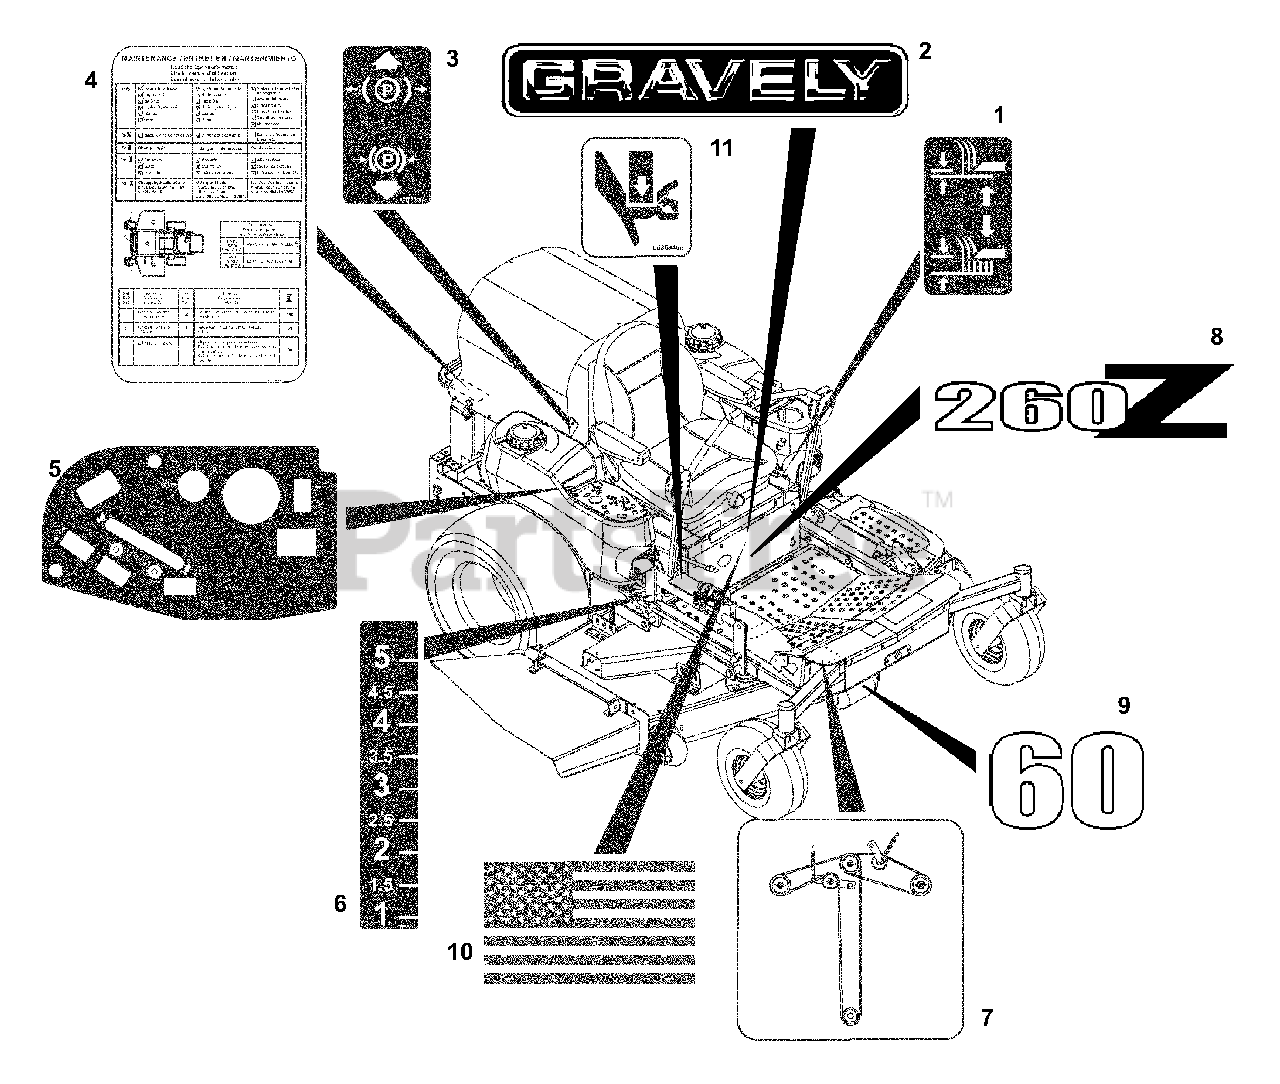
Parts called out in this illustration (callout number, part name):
1	Decal, Lift Lever
2	Decal, 15" Gravely Logo
3	Decal, Parking Brake Lever
4	Decal, Service Instructions
5	Decal, Diesel Control Panel
5	Decal, Control Panel
6	Decal, Height of Cut
7	Decal, Belt Diagram
8	Decal, PM-260Z
8	Decal, PM-272Z
9	Decal, 60
9	Decal, 72
10	Decal, American Flag
11	Decal, Pinch Point
